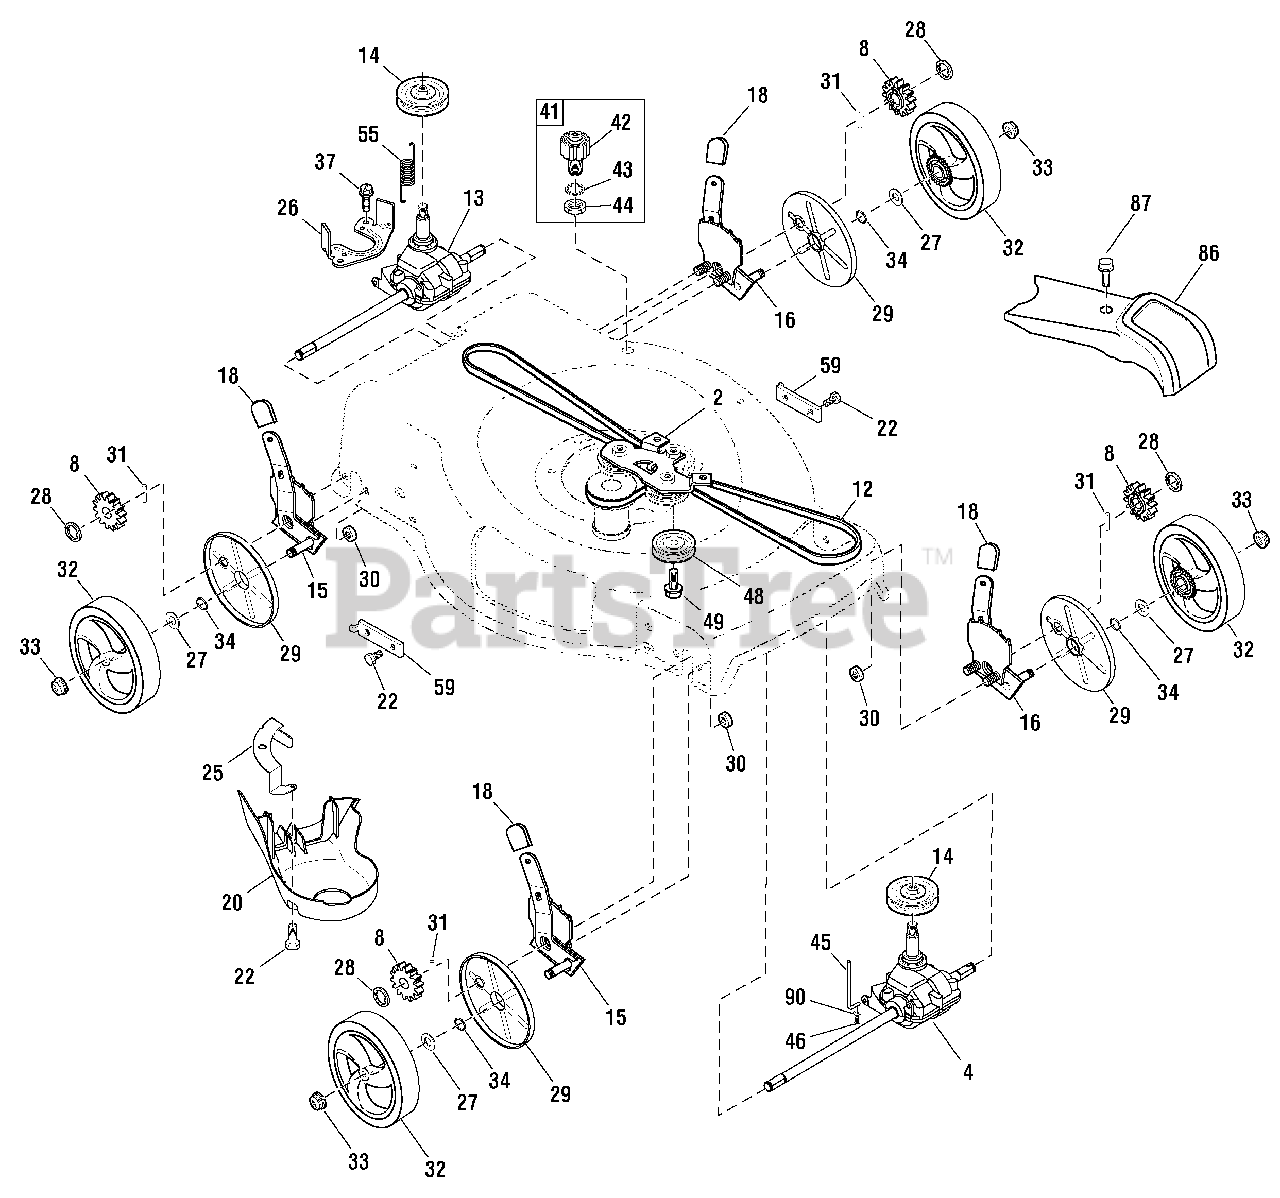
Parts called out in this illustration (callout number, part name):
2	BRACKET, Mounting, Idler Pulle
4	GEARCASE ASSEMBLY, Front
12	BELT, Drive
13	GEARCASE ASSEMBLY, Rear
14	PULLEY, Drive
15	BRACKET, Height Of Cut, Right
16	BRACKET, Height Of Cut, Left
18	KNOB, Wheel Adjust
20	COVER, Debris
22	SCREW, 5/16-18
25	BRACKET, Mounting, Debris Shield
26	BELT GUIDE, Gearcase, Rear
27	WASHER, Flat
28	E-RING, 7/16
29	DUST COVER, Wheel
30	NUT, Hex
31	PAWL, Drive
32	WHEEL ASSEMBLY
33	NUT, Flangelock, 3/8-16
37	SCREW, Hi-Lo Thread, #12 x 5/8
41	KIT, Washout Port
42	WASHOUT PORT
43	WASHER, Lock, Internal Tooth
44	NUT, Lock, With O-Ring
45	BELT GUIDE, Gearcase, Front
48	PULLEY ASSEMBLY, Idler
49	SCREW, Mounting, Idler Pulley
55	SPRING, Tension
59	BRACKET, Support
86	COVER, Drive
87	SCREW
90	WASHER, Flat, 5/16
